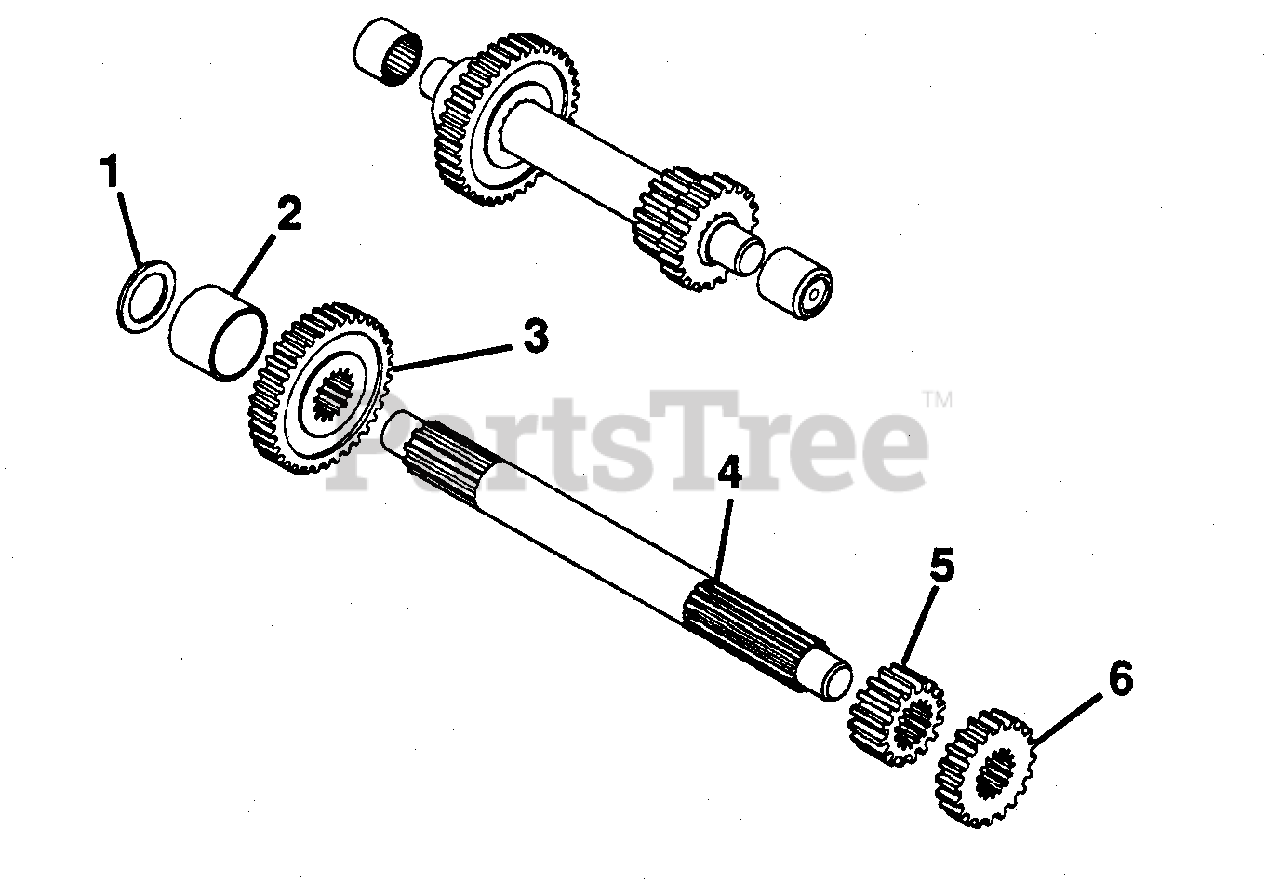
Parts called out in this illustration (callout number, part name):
1	Brg, Thrust Race .627 x 1.115 x .094
2	Spacer, 1.027 x 1.125 x .457
3	Gear
4	Shaft, Splined
5	Gear, 10 DP 16 Teeth x .750
6	Gear, 10 DP 20 Teeth x .600
